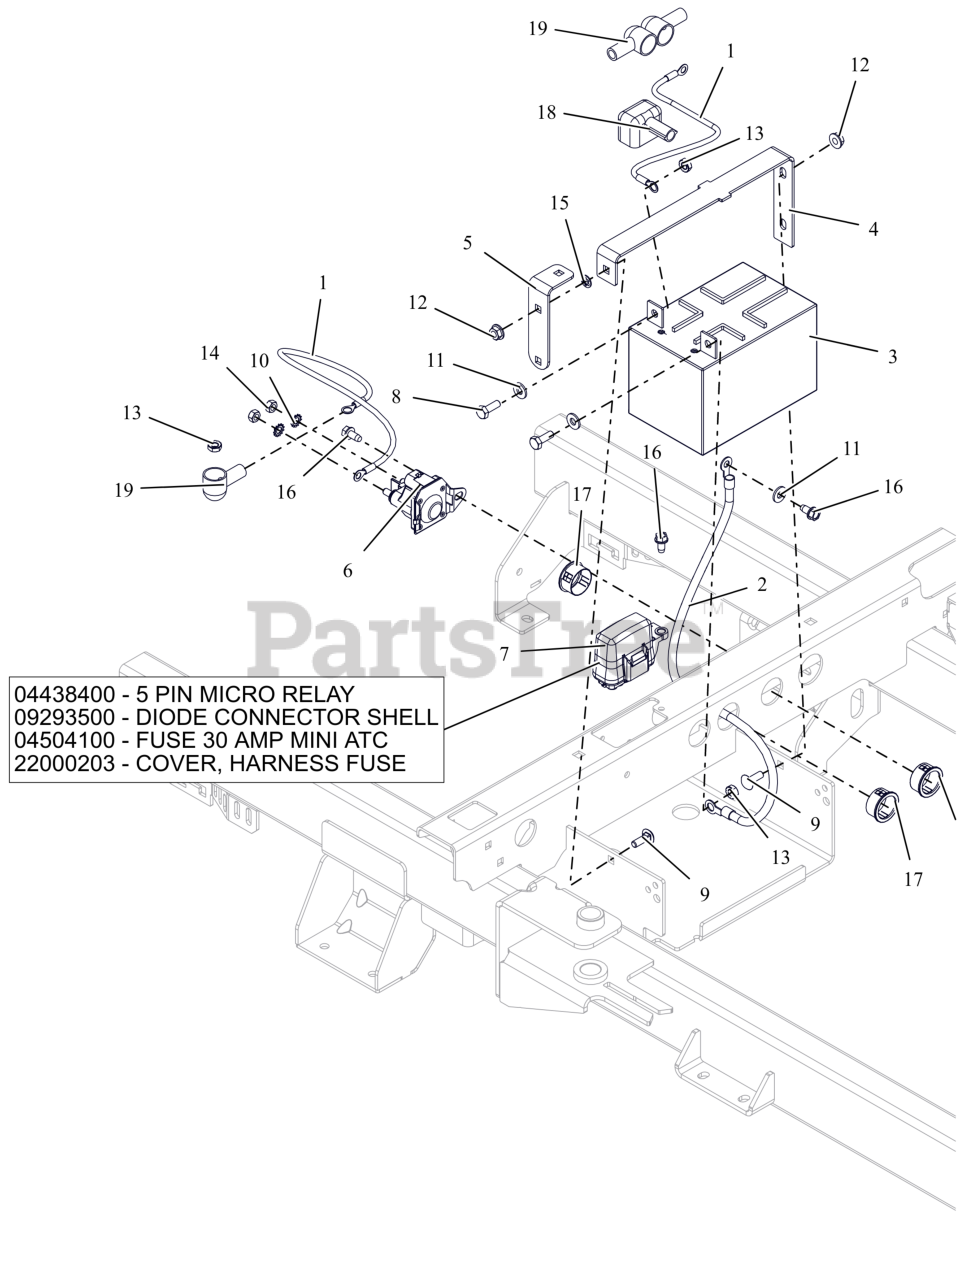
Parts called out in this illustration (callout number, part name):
1	CABLE,POS W/2 1/4 RING 15.0 LG
2	CABLE-NEGATIVE BATTERY 24.00"
3	BATTERY, 12V 12A-190CCA
4	BRKT, BATTERY HOLD-DOWN
5	BRKT, BATTERY HOLD DOWN
6	SOLENOID, STARTER (SEALED)
7	HARNESS, WIRE
7	RELAY,MICRO5 TERML W/RESISTOR
7	DIODE, CONNECTOR SHELL
7	FUSE,30 AMP MINI-ATC
7	COVER, FUSE
8	BLT, HEX .25-20X.75 G5 ZCC
9	BLT, RHSN .25-20X.750 G5 ZCC
10	WSHR,LK-EXT.262X.502X.026 ZCC
11	WSHR,FLT .281X.625X.065 ZCC
12	NUT-LK-TOP-FLG .250-20 GF ZCC
13	NUT-KEPS .250-20 ZCC
14	NUT-STD M6-1.0 ZCC
15	NUT-PUSH .25X.50 O.D.
16	SCR-TAP .25-20X.50 HWH ZCC
17	BSHG, PANEL SNAP .937X1.11X.56
18	INSULATOR
19	BOOT, EYELET TERMINAL
